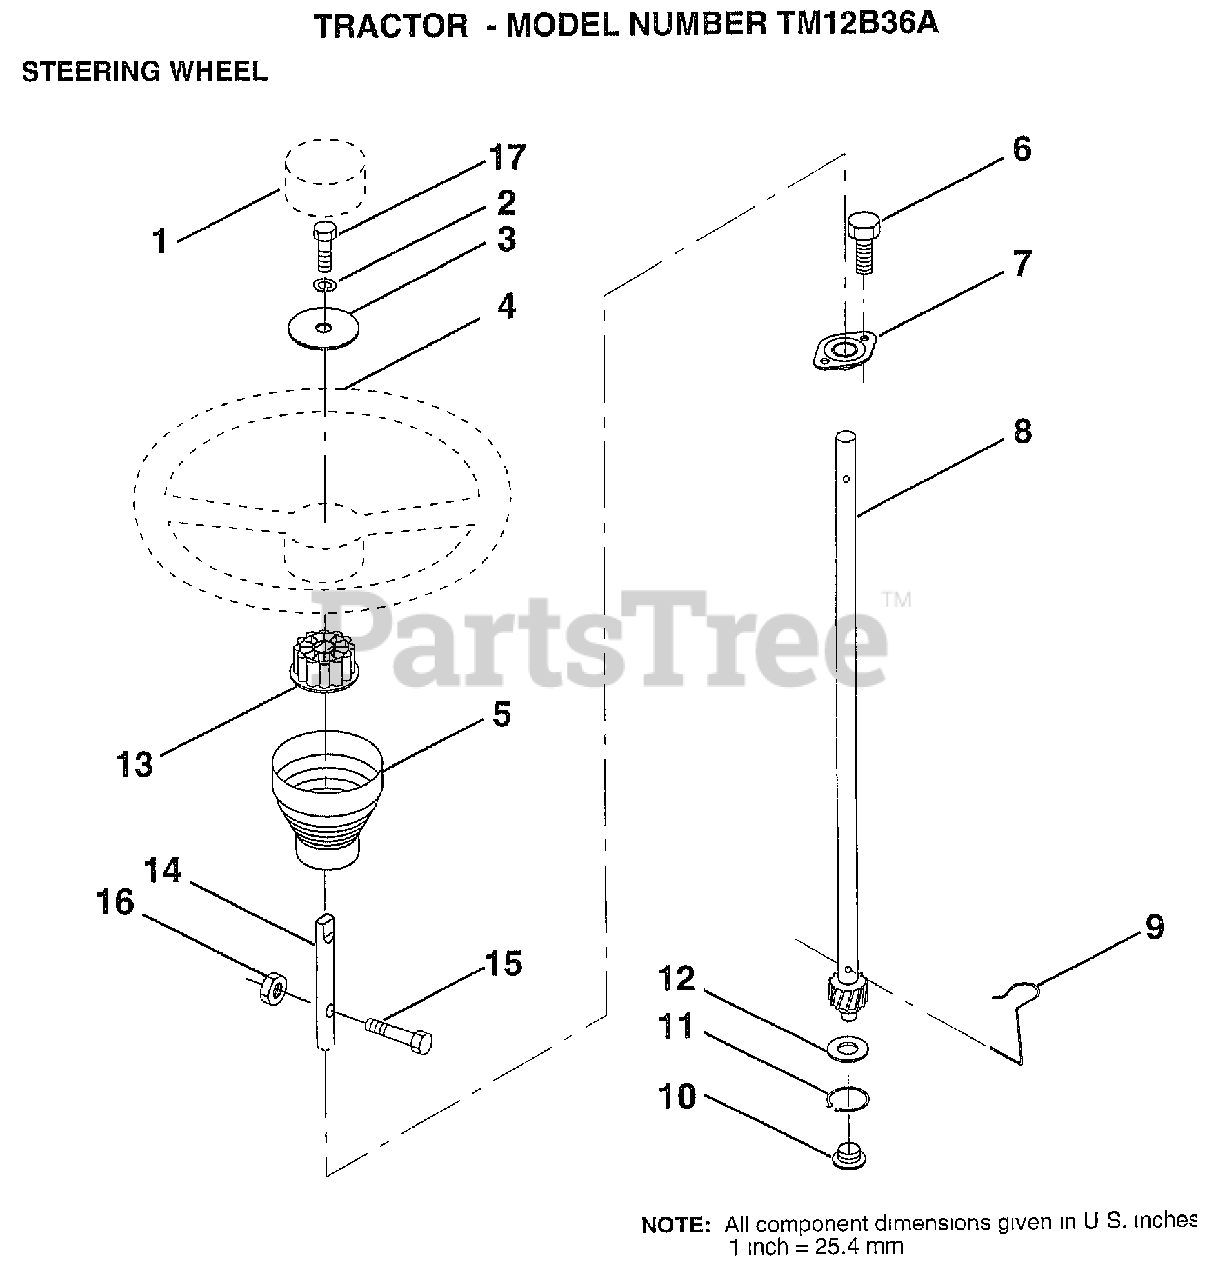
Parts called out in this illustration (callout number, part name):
1	ST WHL INSERT CAP
2	LOCKWASHER
3	WASHER T
5	SLEEVE STEERING
6	"SCREW-TT,10-32 FL"
7	BUSHING.STR.623
8	SHAFT.STEERING.LR
9	STEERING CLIP
10	BUSHING STEER LWR
11	RING
12	WASHER LT
13	ADAPTER LT
14	EXT SHAFT STEERIN
15	BOLT
16	NUT
17	BOLT
